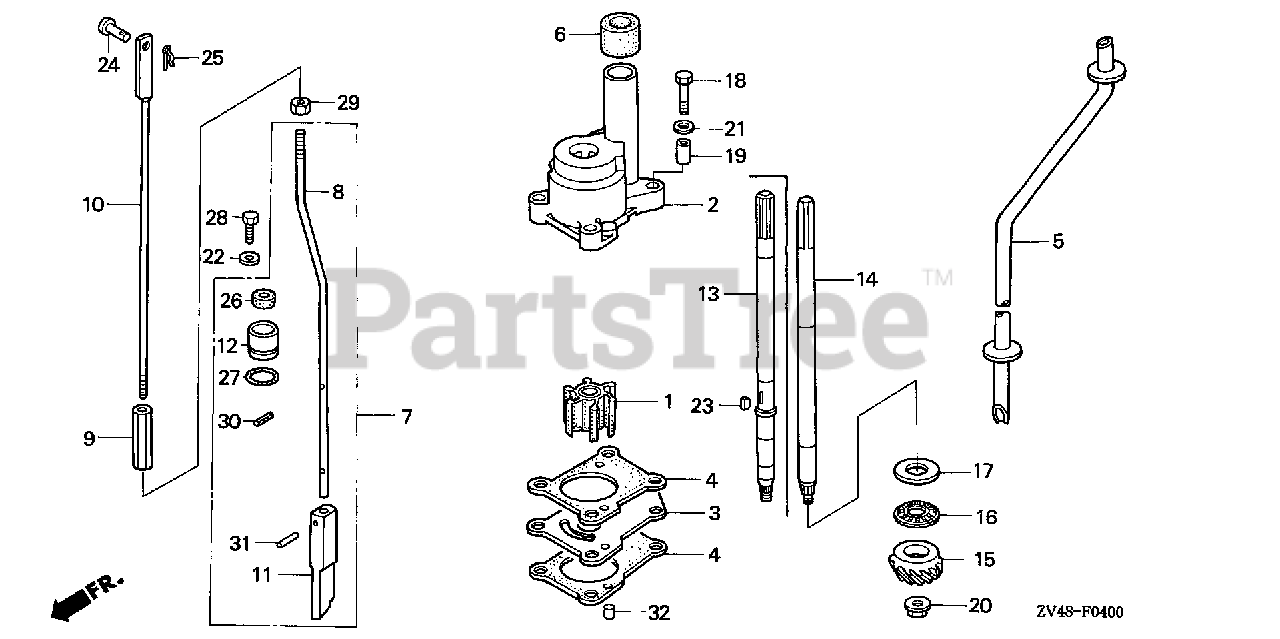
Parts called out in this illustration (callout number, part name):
1	IMPELLER, PUMP
2	HOUSING, IMPELLER
3	COVER, IMPELLER
4	GASKET, IMPELLER
5	TUBE, WATER
6	RING, WATER TUBE SEAL
7	ROD, SHIFT (S)
8	ROD B, SHIFT (S)
9	JOINT, SHIFT ROD
10	ROD A, SHIFT
12	HOLDER, SEAL
14	SHAFT, VERTICAL (S)
15	PINION (13T)
16	WASHER A, THRUST BEARING (2.00MM)
17	WASHER, THRUST BEARING A (3.00MM)
17	WASHER, THRUST BEARING B (3.03MM)
17	WASHER, THRUST BEARING C (3.06MM)
17	WASHER, THRUST BEARING D (3.09MM)
18	BOLT, HEX. (6X28)
19	COLLAR B, DISTANCE
20	NUT, SPECIAL (8MM)
21	WASHER, PLAIN (6MM)
22	WASHER, PLAIN (6MM)
23	KEY, WOODRUFF (16X12)
24	PIN (5X28)
25	PIN, LOCK (5MM)
26	SEAL, WATER (6MM)
27	O-RING (15X2.5)
28	BOLT, HEX. (6X12)
29	NUT, HEX. (6MM)
30	PIN, SPRING (2.5X12)
31	ROLLER (2.5X11.8)
32	ROLLER (4X10)
